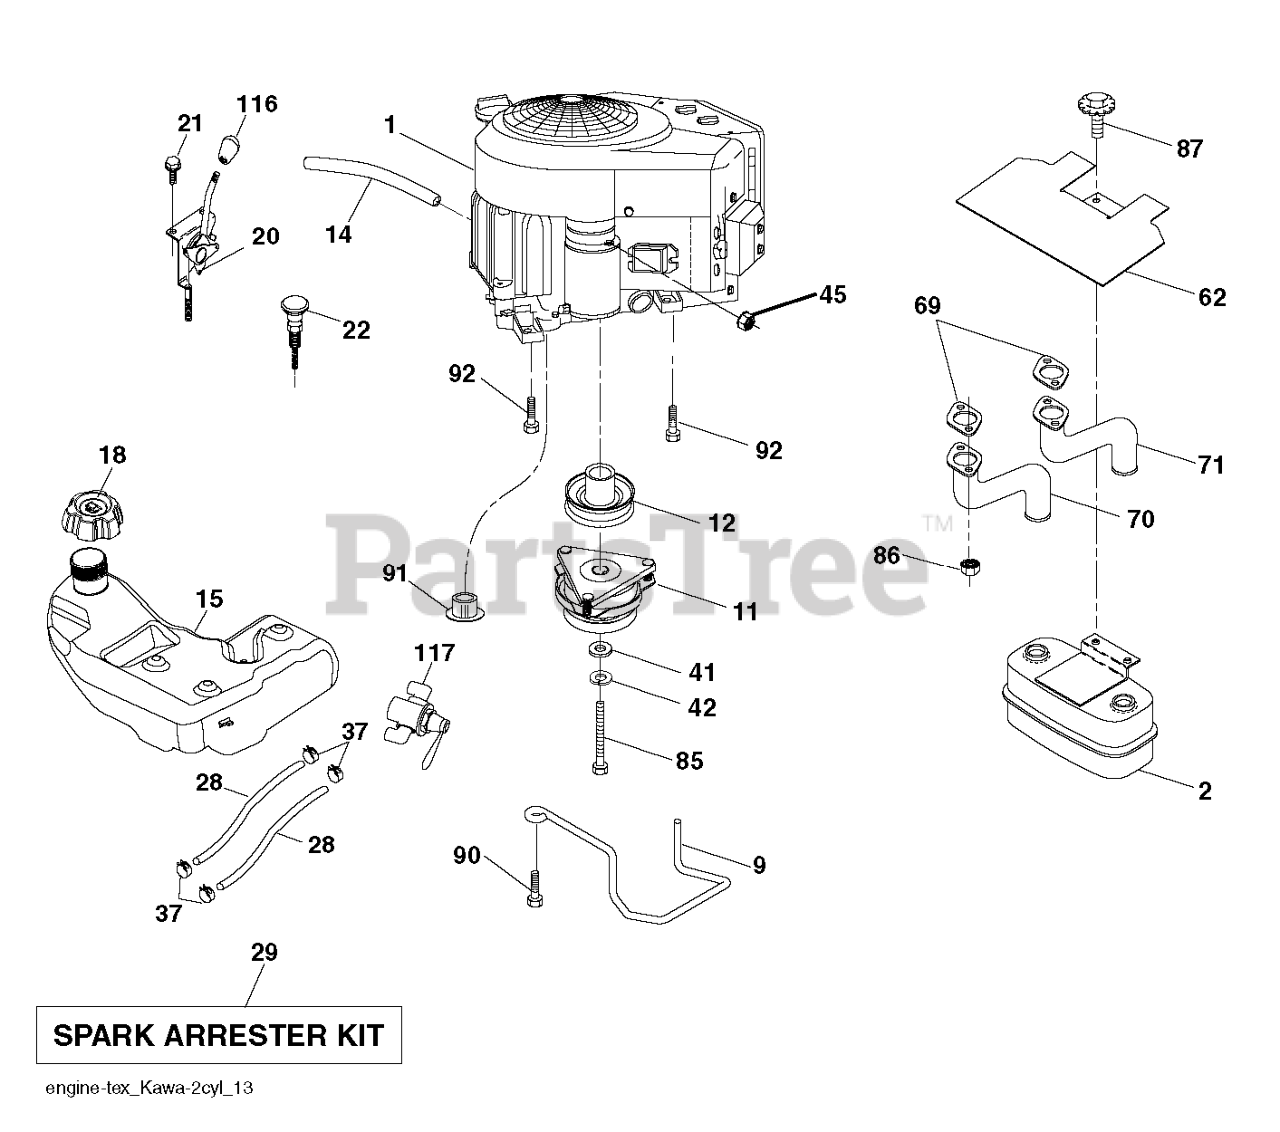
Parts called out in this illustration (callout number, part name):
2	MUFFLER.TWIN.CYL.LOW.TONE
9	KEEPER BELT ENGINE
11	CLUTCH MZ ZTR GT.48/54"1.125"
12	PULLEY ENGINE
14	TUBE, DRAIN OIL ASM.
18	CAP.FL.R.3'N/CARB.H.CROWN.498
20	CONTROL.THROTTLE.PRO.
21	SCREW.#10 X 0.750.BOS
22	CONTROL.CHOKE.ERGO.PUSH-IN.BLA
28	LINE.FUEL.1/4" ROLL
29	KIT.SPARK ARRESTOR 794945 B&S
37	HOSE CLAMP
42	LOCKWASHER
45	NUT
62	SHIELD.HEAT.MUFFLER
70	TUBE.EXHAUST.LH.FR961/FR730
71	TUBE.EXHAUST.RH.FR961/FR730
85	BOLT HEX 7/16-20 X 3.75 GR. 5
86	SCREW.SOCKET.HEAD.5/16-18
87	BOLT.5/16-18UNCX1.W/SEMS.BLK
90	SCREW 3/8-16X1
91	BUSHING.1.375OD
92	SCREW.3/8-16
116	KNOB - SHIFT
117	VALVE FUEL RESERVE
